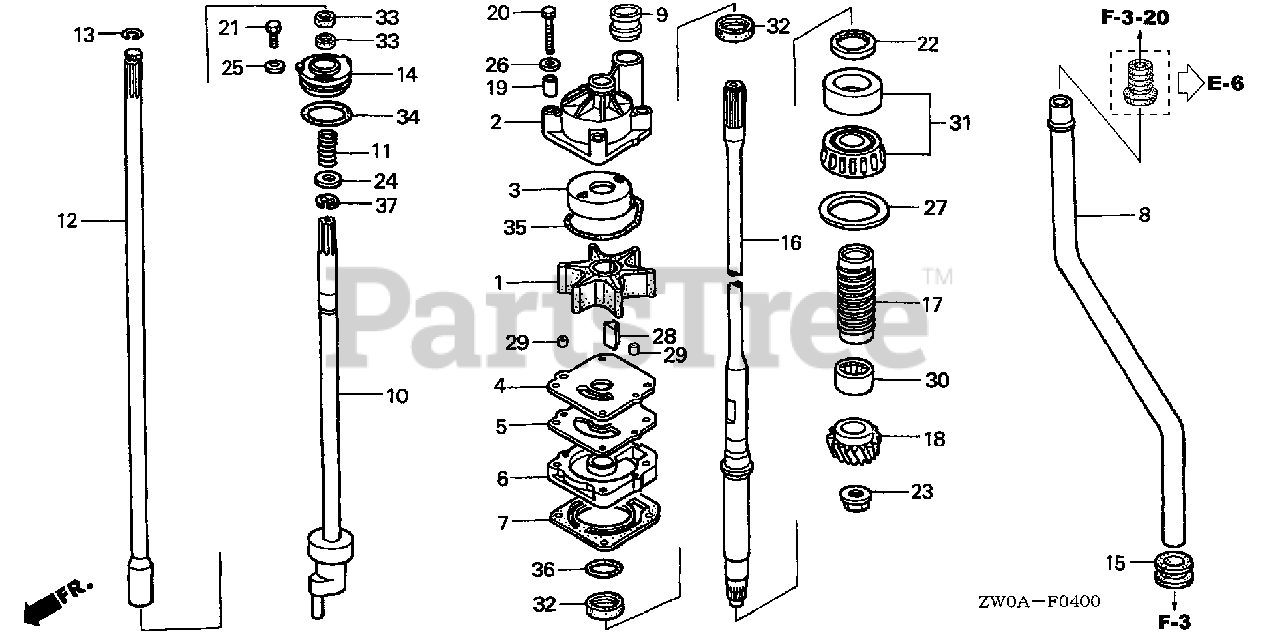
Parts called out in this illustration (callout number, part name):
1	IMPELLER, PUMP
2	HOUSING, IMPELLER
3	LINER, PUMP
4	COVER, IMPELLER
5	GASKET B, IMPELLER
6	HOUSING, WATER PUMP
7	GASKET, WATER PUMP
8	TUBE, WATER (L)
9	RING, WATER TUBE SEAL
10	ROD, SHIFT (L)
11	SPRING, SHIFT ROD
12	ROD A, SHIFT
13	RING, STOPPER
14	HOLDER, SHIFT ROD
15	GROMMET, EXTENSION CASE
16	SHAFT, VERTICAL (L)
17	SLINGER, OIL
18	GEAR, PINION (12T)
19	COLLAR, DISTANCE
20	BOLT, HEX. (8X55)
21	BOLT, HEX. (6X12)
22	NUT, LOCK (64MM)
23	NUT, HEX. (16MM)
24	WASHER, PLAIN (12MM)
25	WASHER, PLAIN (6MM)
26	WASHER (8MM)
27	SHIM A, GEAR (0.10)
27	SHIM B, GEAR (0.15)
27	SHIM C, GEAR (0.30)
27	SHIM D, GEAR (0.50)
28	KEY, WOODRUFF
29	PIN, DOWEL (6X10)
30	BEARING, NEEDLE (1-1/8X1-1/2X1-1/4)
31	BEARING, TAPER ROLLER (30X62X40)
32	SEAL, WATER (23X36X6)
33	SEAL, WATER (12X21X6)
35	O-RING, WATER PUMP
36	O-RING (58.5X3.5)
37	E-RING (10MM)
